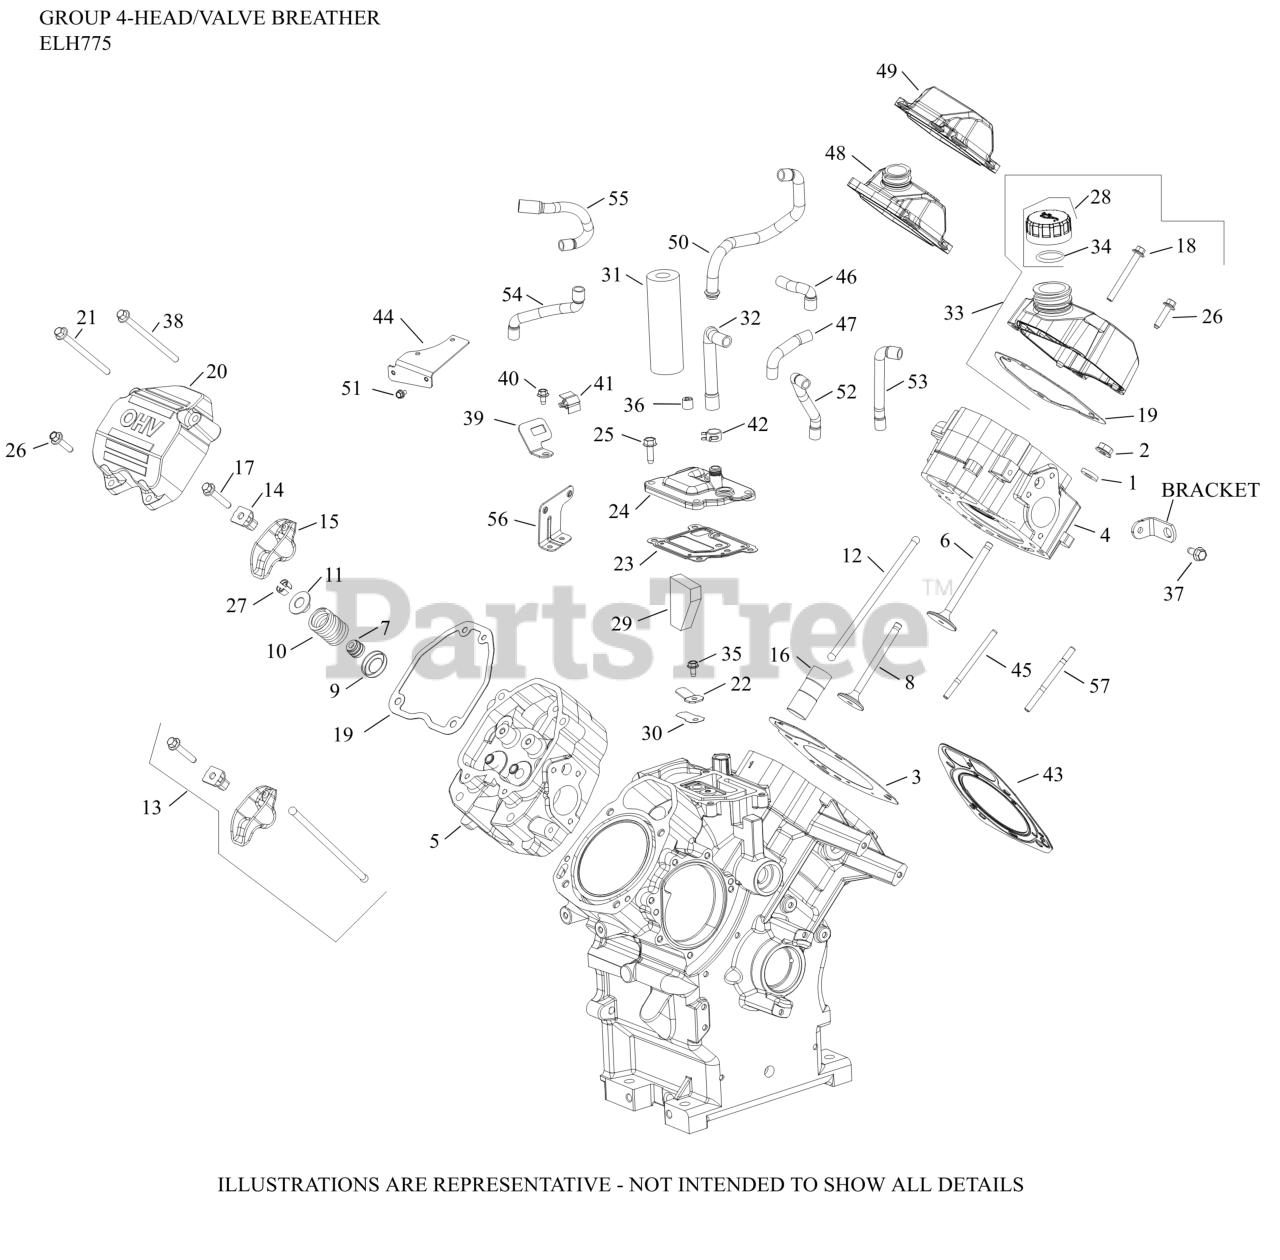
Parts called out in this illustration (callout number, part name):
1	WASHER, FLAT 5/16"
2	NUT, FLG M8X1.25
3	KIT,CYL HD GASKET #2SIDE-USE 66 841 04-S
4	KIT, CYLINDER HEAD (#1 SIDE)
5	KIT, CYLINDER HEAD (#2 SIDE)
6	VALVE, INTAKE (STD)
6	VALVE, INTAKE (.25)
7	SEAL, VALVE BAND
8	VALVE, EXHAUST
8	VALVE, EXHAUST (.25)
9	RETAINER, SPRING
10	SPRING, VALVE
11	CAP, VALVE SPRING
12	ROD, PUSH
13	KIT, VALVE TRAIN
14	PIVOT, ROCKER ARM
15	ARM, ROCKER
16	LIFTER, VALVE HYDRAULIC-USE 25 351 11-S
17	SCREW, FLG (BLACK) M6X1.0X34
18	SCREW, FLG M6X1.0X55
19	GASKET, VALVE COVER
20	KIT, ROCKER COVER
21	SCREW, FLG M6X1.0X80
22	RETAINER, REED
23	GASKET, BREATHER
24	COVER, BREATHER
25	SCREW, THREAD FORMING
26	SCREW, FLG M6X1.0X25
27	KIT, RETAINER
28	KIT, OIL FILL CAP (YELLOW)
29	FILTER, BREATHER
30	REED, BREATHER-(#2440206S)
30	REED, BREATHER
32	HOSE, BREATHER
33	KIT, LH OIL FILL VALVE COVER
34	O-RING, DIPSTICK
35	SCREW, FLG THD FRM M5X.8X10
37	SCREW, THREAD FORMING
39	BRACKET, OXYGEN SENSOR
40	SCREW, THREAD FORMING
41	CLIP, O2 SENSOR
42	SPRING CLAMP, HOSE
